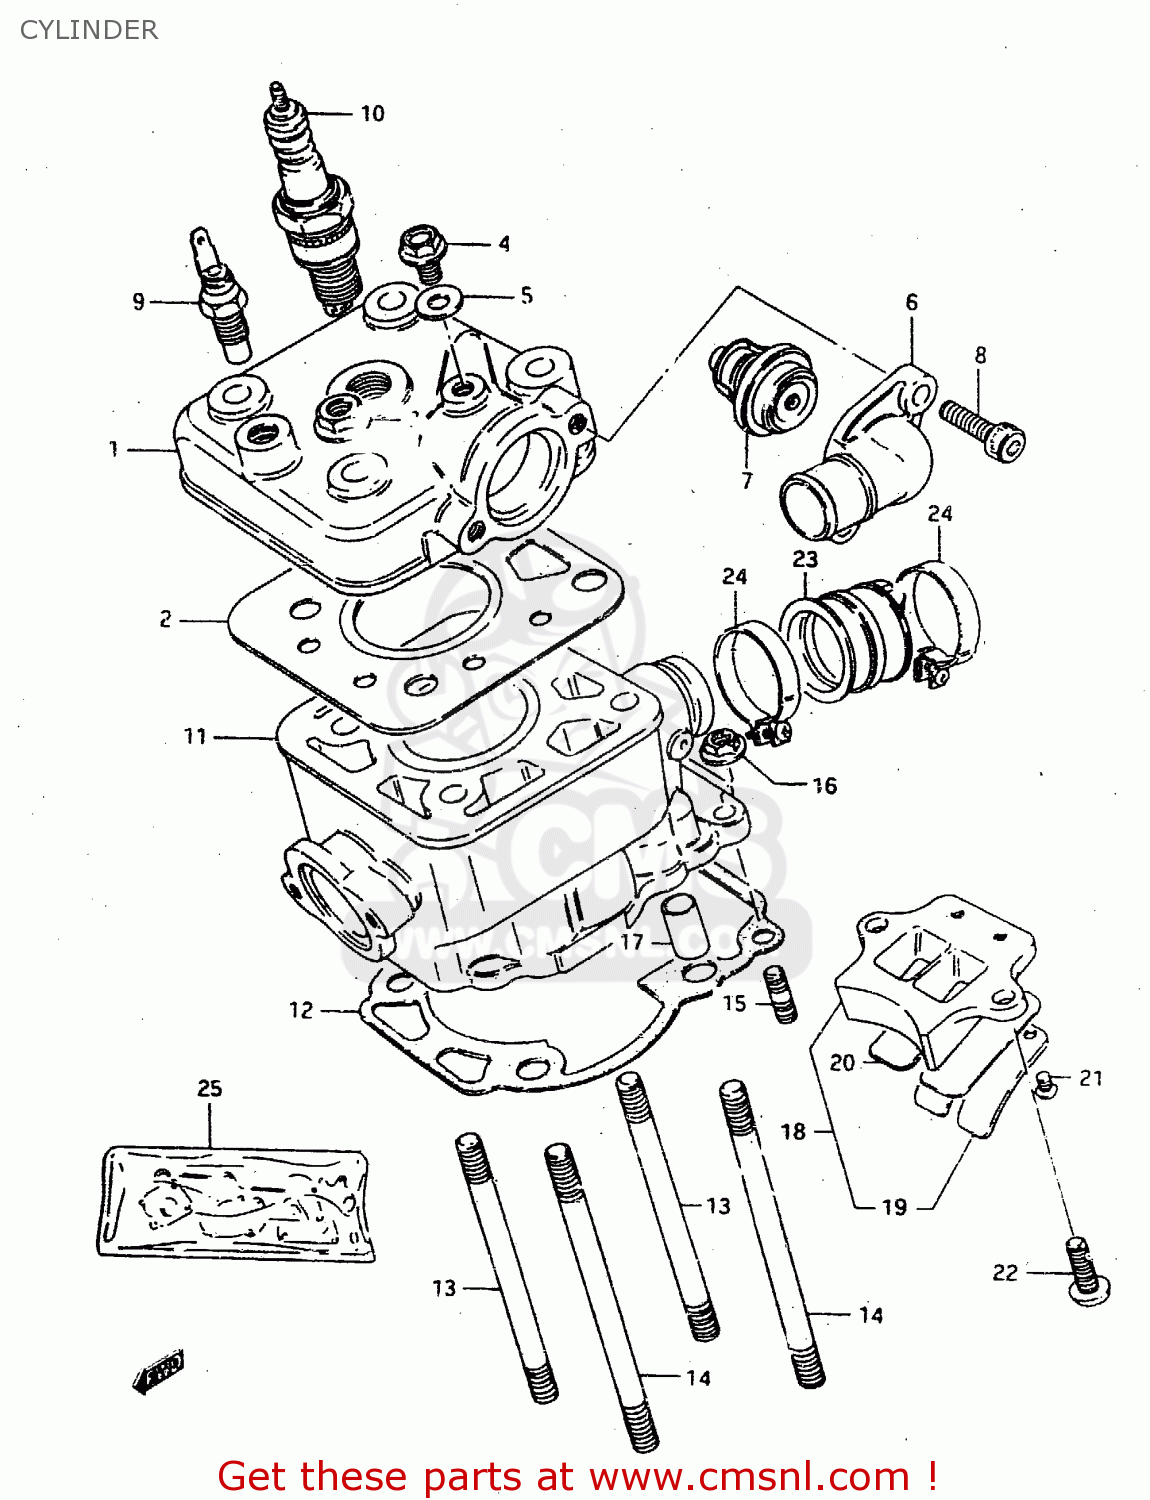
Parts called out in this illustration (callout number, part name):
1	HEAD,CYLINDER
2	GASKET,CYLINDER HEAD (NAS)
3	NUT
4	UNION
5	GASKET(6.2X11X1).2 (NAS)
6	COVER,THERMOSTAT
7	THERMOSTAT,WATER
8	BOLT,CRKCASE,R
9	GAUGE ASSY, WATER TEMP
10	PLUG,SPARK(BPR8ES)
11	CYLINDER
12	GASKET,CYLINDER (NAS)
13	BOLT,STUD
14	BOLT,STUD
15	STUD BOLT
16	NUT
17	PIN
18	VALVE ASSY,REED
19	STOPPER,REED VALVE
20	VALVE,REED
21	SCREW
22	SCREW 6X16
23	PIPE,INTAKE
24	CLAMP
25	GASKET SET (NAS)
